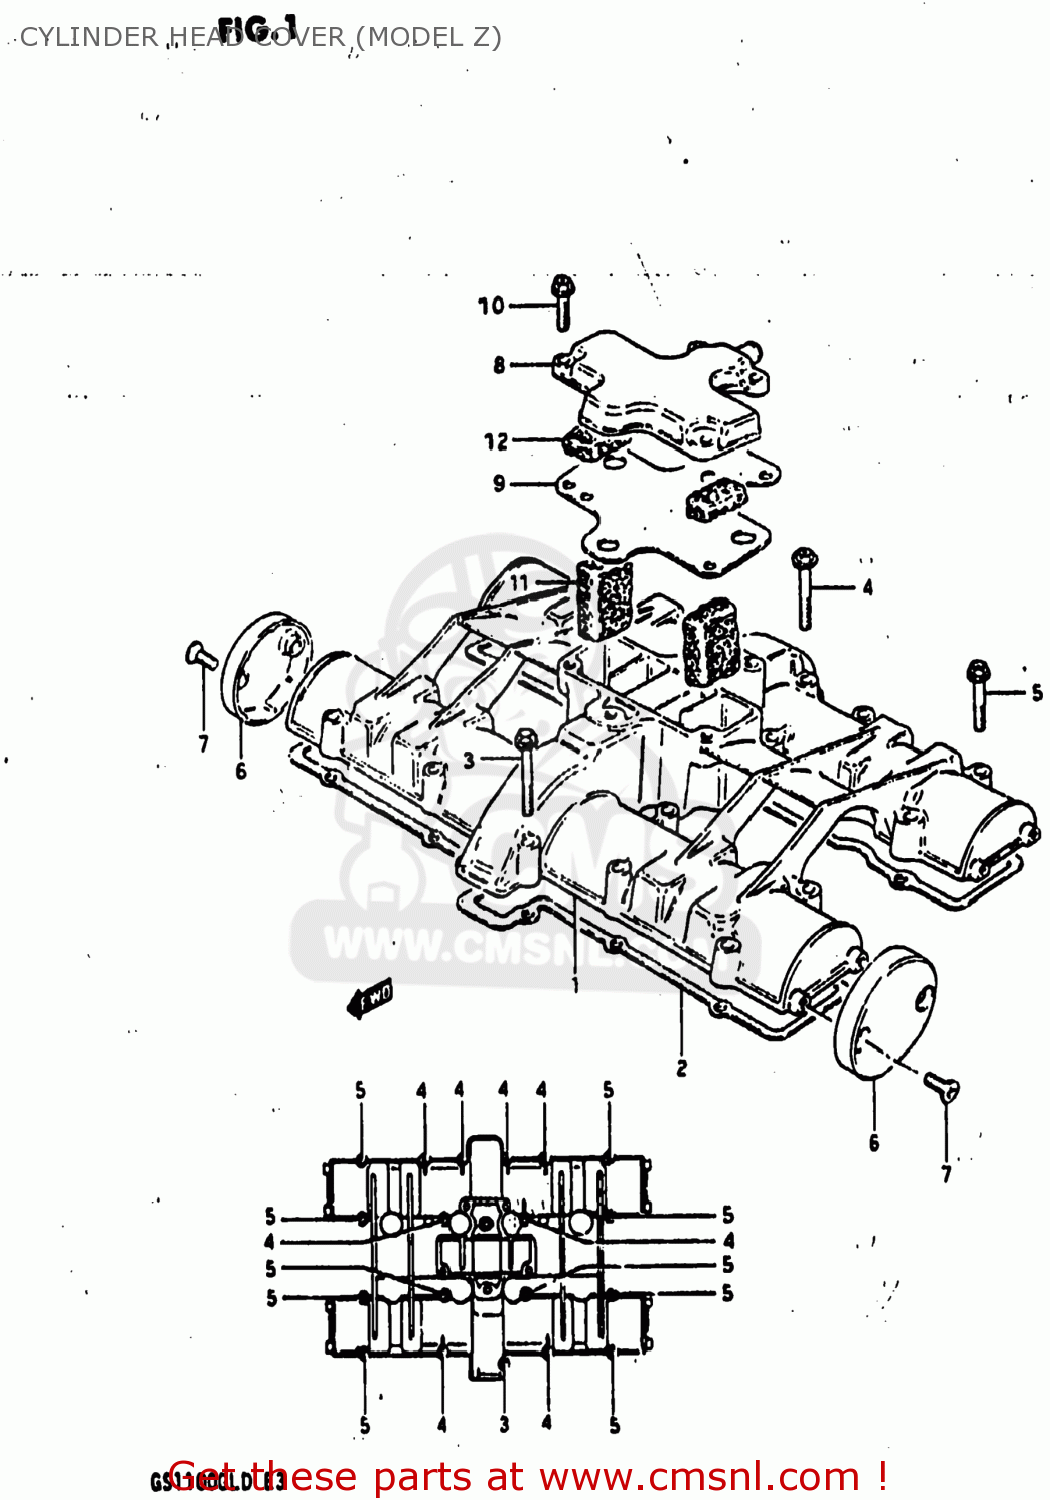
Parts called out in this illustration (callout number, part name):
1	COVER,CYLINDER HEAD
2	GASKET,CYLINDER HEAD COVER (MCA)
3	BOLT,UNDER
4	BOLT
5	BOLT 6X35
6	CAP,CYLINDER HEAD COVER
7	SCREW(5X12)
8	COVER,BREATHER
9	GASKET (MCA)
10	BOLT
11	COVER,BREATHER
12	SEPARATOR,OIL BREATHER
